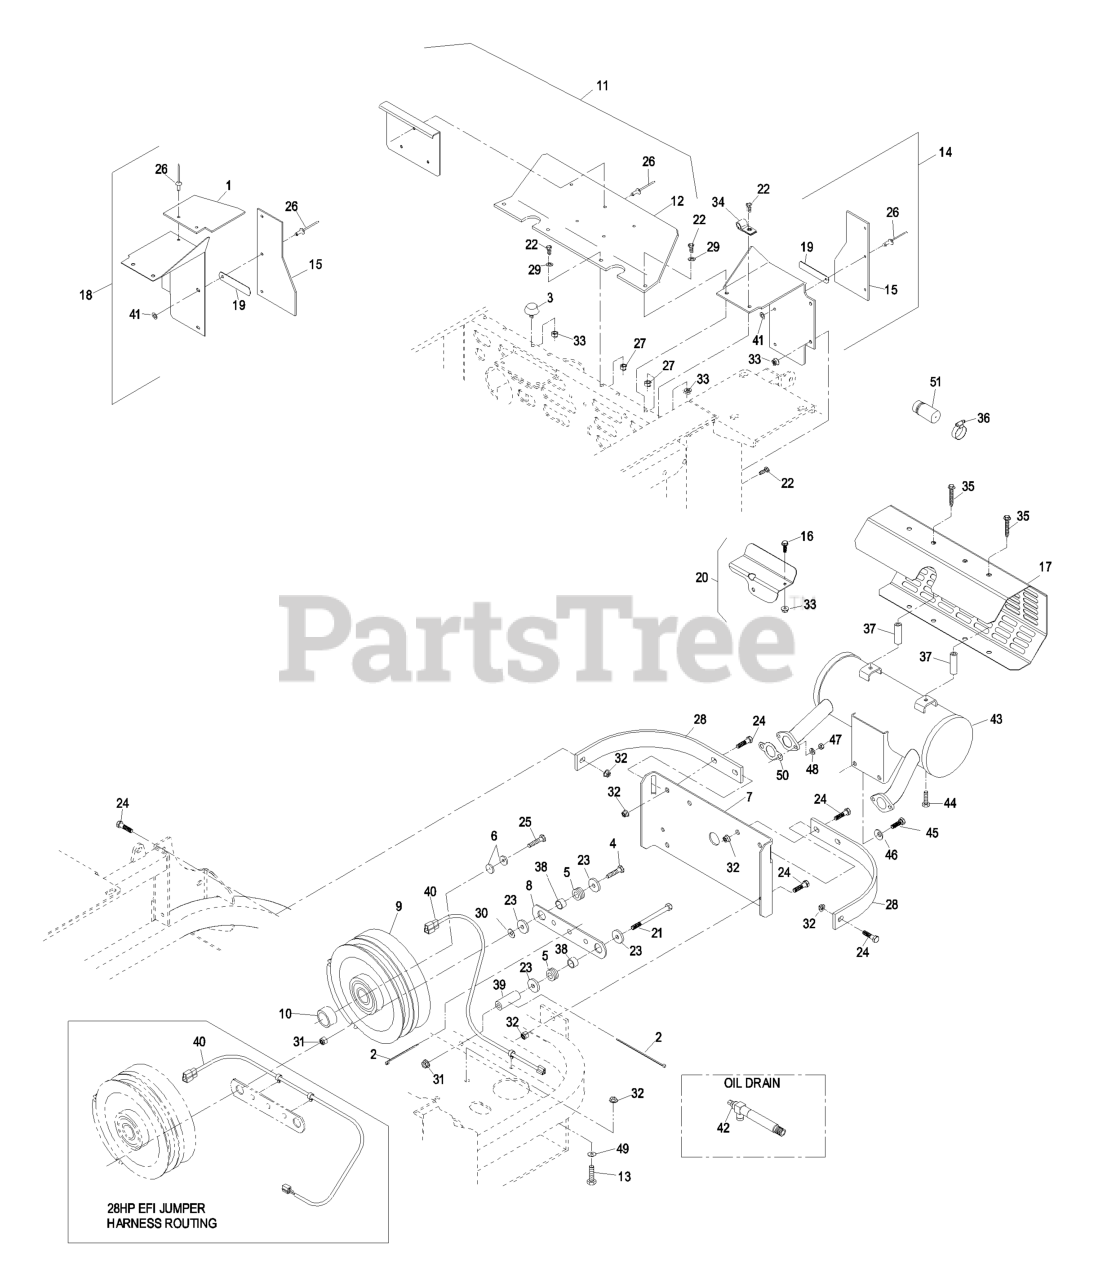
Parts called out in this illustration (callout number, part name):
1	BAFFLE-COOLER, ENGINE
2	TIE-PLASTIC
4	SCREW-HH
5	GROMMET
6	WASHER-SPRING
7	GUARD-CLUTCH
8	STRAP-CLUTCH, BRAKE
9	KIT-CLUTCH
10	SPACER-CLUTCH
12	SHIELD-ENGINE
13	SCREW-HH
15	SHIELD-ENGINE
16	SCREW-HH
17	GUARD-MUFFLER
18	RH SHIELD ASM
19	CLIP-BAFFLE, REAR
20	CABLE HEAT SHIELD KIT
21	SCREW-HH
22	SCREW-HH
24	SCREW-HH
25	SCREW-HH
26	RIVET-POP
27	NUT-LOCK, NI
28	STRAP-GUARD
29	WASHER-FLAT
30	WASHER-FLAT
32	NUT-HHF, WHIZ
34	CLIP-LOOM
35	SCREW-HWH
36	CLAMP-MUFFLER
39	SPACER-ANCHOR, CLUTCH
40	KIT,CLUTCH JUMPER HARNESS
41	WASHER-FLAT
42	VALVE-OIL DRAIN, LONG
43	KIT,MUFFLER KOHLER
44	SCREW
45	SCREW-HH
46	SCREW-HH
47	NUT-HEX
48	WASHER-LOCK
49	WASHER-BELLEVILLE
51	ARRESTER-SPARK
